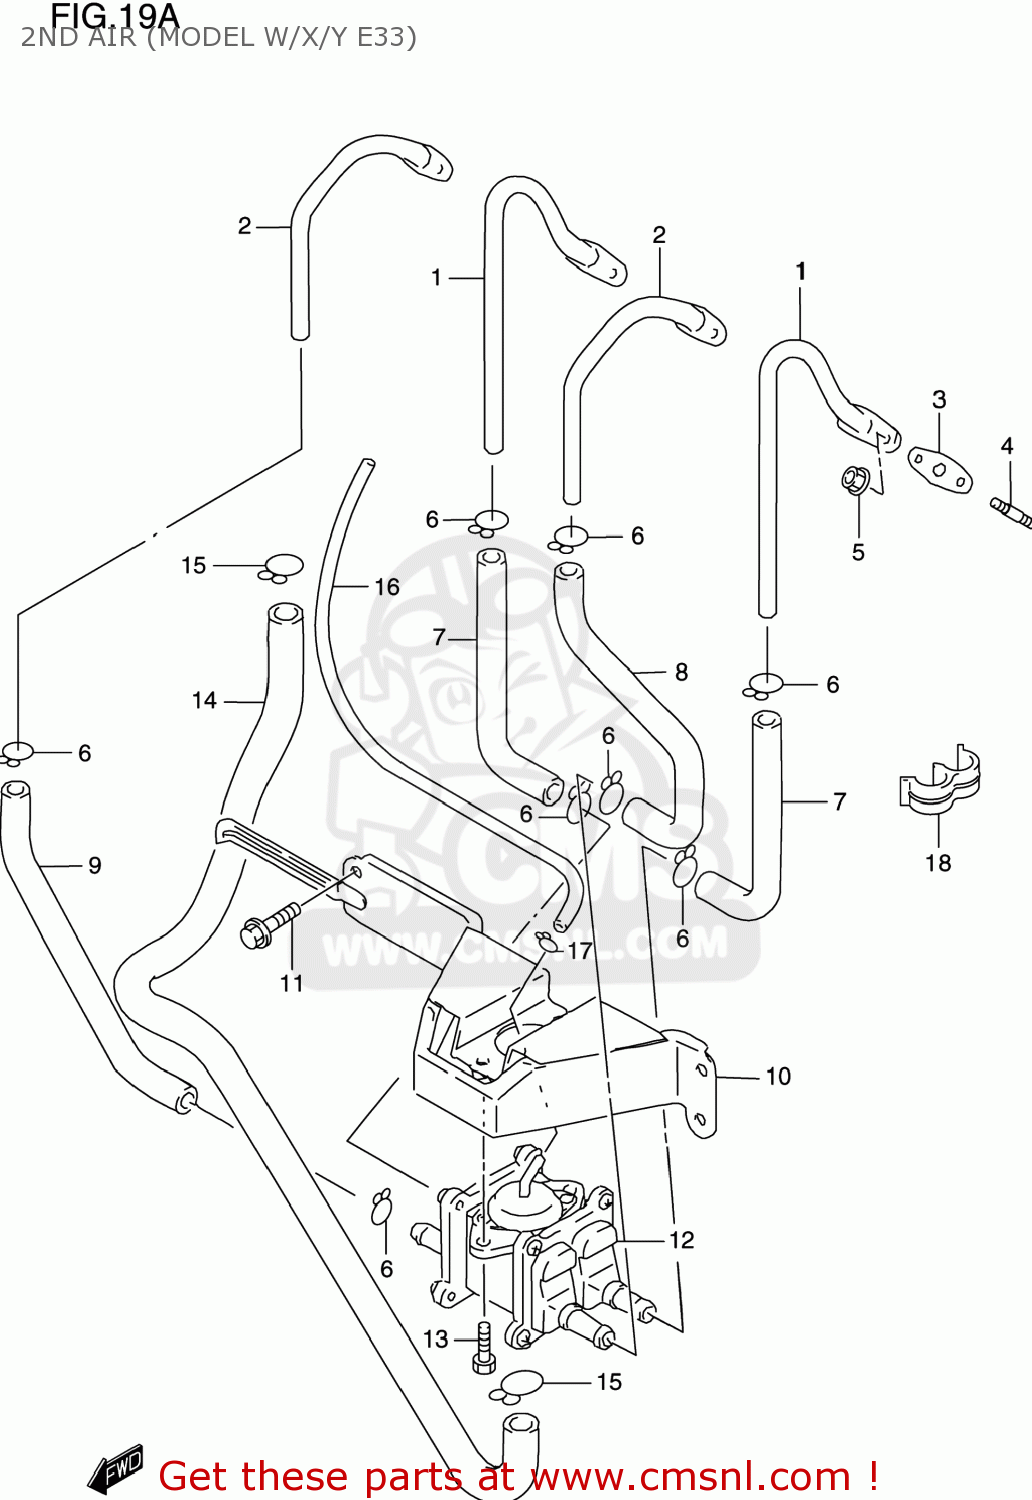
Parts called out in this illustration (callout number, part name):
1	PIPE COMP,SECOND AIR NO.1
2	PIPE COMP,SECOND AIR NO.2
3	GASKET,SECOND AIR PIPE (N (NAS)
4	STUD BOLT
5	NUT
6	CLIP
7	HOSE,2ND AIR VALVE NO.1
8	HOSE,2ND AIR VALVE NO.2
9	HOSE,2ND AIR VALVE NO.4
10	BRACKET,SECOND AIR VALVE
11	BOLT 6X12
12	VALVE ASSY,2ND AIR
13	BOLT,OIL FILLE
14	HOSE,SECOND AIR CLEANER
15	CLIP
16	HOSE(4X7X2000)
17	CLIP
18	CLAMP
